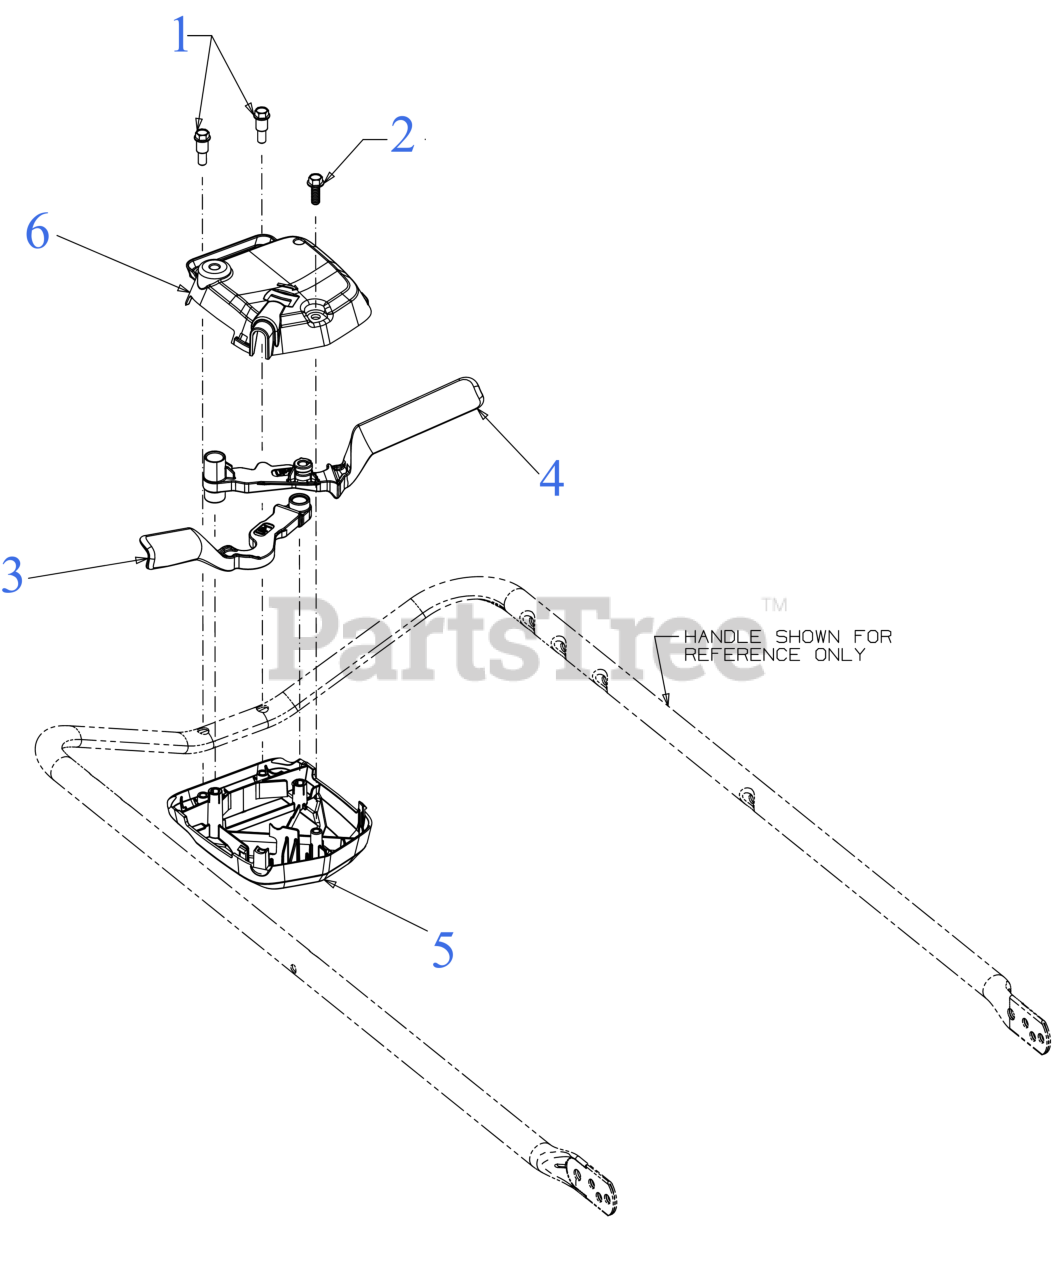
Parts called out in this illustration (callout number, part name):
1	SHOULDER SCREW 1/4-15 x .970
2	SCREW 1/4-15 x .750
3	CONTROL LEVER (LH)
4	CONTROL LEVER (RH)
5	UPPER CONTROL HOUSING
6	LOWER CONTROL HOUSING
